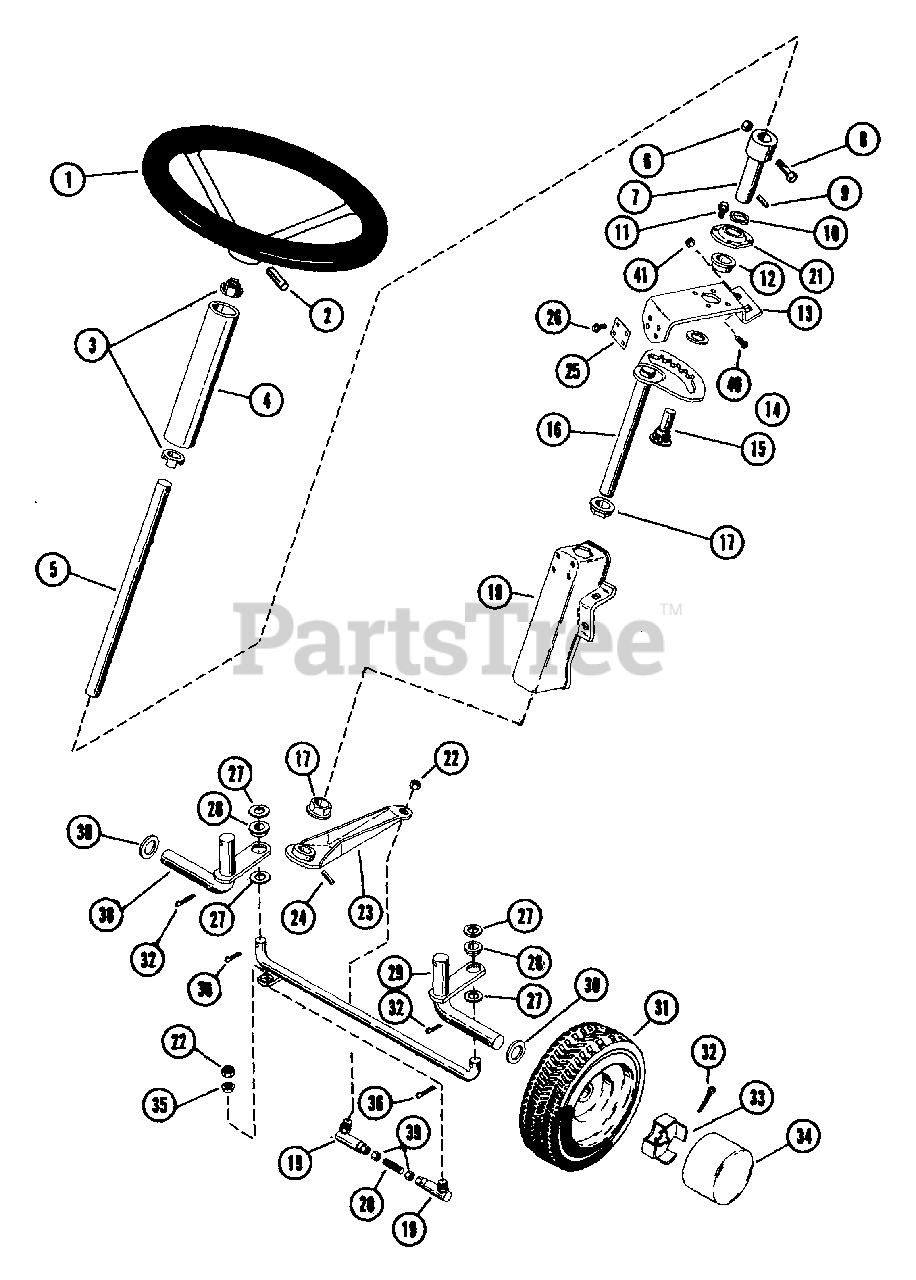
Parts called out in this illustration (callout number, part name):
1	WHEEL
2	PIN-ROLL .250X1.25
3	EXTENSION CUP
4	STEER COVER
5	STEERING SHAFT EXT
6	NUT-LK-CTR .250-20 PL
7	STEERING SHAFT
8	BLT-HEX .25-20X1.50 PL GR5
9	PIN-ROLL .188X1.00
10	WAVE WASHER .531X.781X.125FH
11	SCR-TAP 10-24X.25 CRSLPH PL 1A
12	BSHG-FLG .625X1.156X.375 SI
13	STEERING SUPPORT
14	WSHR-FL-STL .630X1.005X.062 PL
15	STEERING PINION
16	STEERING GEAR
17	FLANGE BUSHING
18	DEEP DRAW STEERING BOXES
19	BALL JOINT
20	AXLE
21	RETAINING PLATE
22	NUT-LK-CTR .375-24
23	STEERING ARM
24	PIN-ROLL .188X1.25
26	BLT-SERHFWH .31-18X.75 PL
27	WSHR-FL-STL .505X.875X.024 PL
28	BSHG-FLG.500X.625X.312X.750NY
29	L H WHEEL SPINDLE
30	SPINDLE WASHER
31	FRONT WHEEL ASSEMBLY
31	TIRE 4.10/3.50-4
31	WHL
31	ZERK FITTING
31	BSHG-FLG .750X1.380X.750X1.557
32	PIN-COTR .12 X 1.25 PL
33	SPINDLE CUP
34	HUB CAP
35	BSHG-FLG .372X.500X.312X.625NY
36	PIN-COTR .12X1.0 PL
37	TIE ROD
38	R H WHEEL SPINDLE
39	NUT .375-24 PL
40	BLT-RDHDSQSHNK .31-18X.50 YZ
41	NUT-LK .312-18 GR A PL
